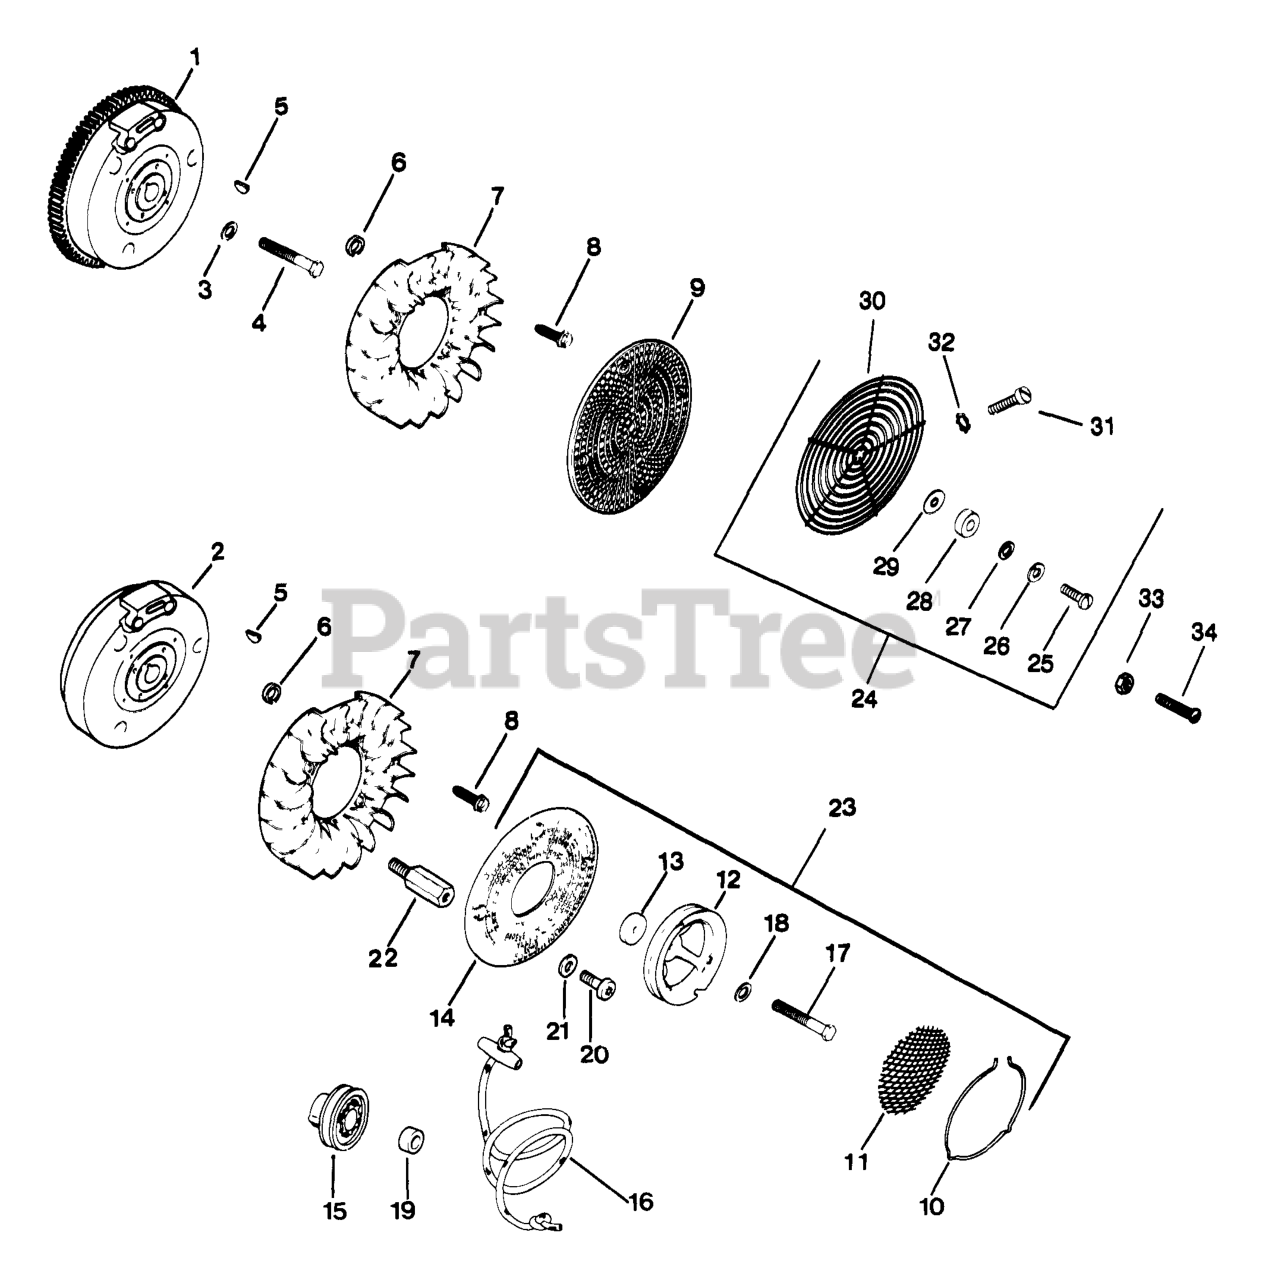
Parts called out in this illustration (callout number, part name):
1	FLYWHEEL - DISCONTINUED
3	WASHER (KM)-USE 12 468 03-S
4	SCREW, MACH 3/8-24X1-1/4"
5	KEY, 3/16" X 1"
8	SCREW, WSH HD 1/4-20X5/8" - DISCONTINUED
9	SCREEN, GRASS
24	KIT, GUARD - DISCONTINUED
25	SCREW, SLT PAN HD 10-24X1" USE 25 086 65-S
26	WASHER, SPRING LOCK #10
29	DIAPHRAGM-DISCONTINUED
31	SCREW, POZ FLS TAP #10-16X3/4" - DISCONTINUED
32	WASHER, EXT TOOTH LOCK #10
33	SCREW, SLT PAN HD 10-24X1" USE 25 086 65-S
34	NUT USE 25 100 11-S
